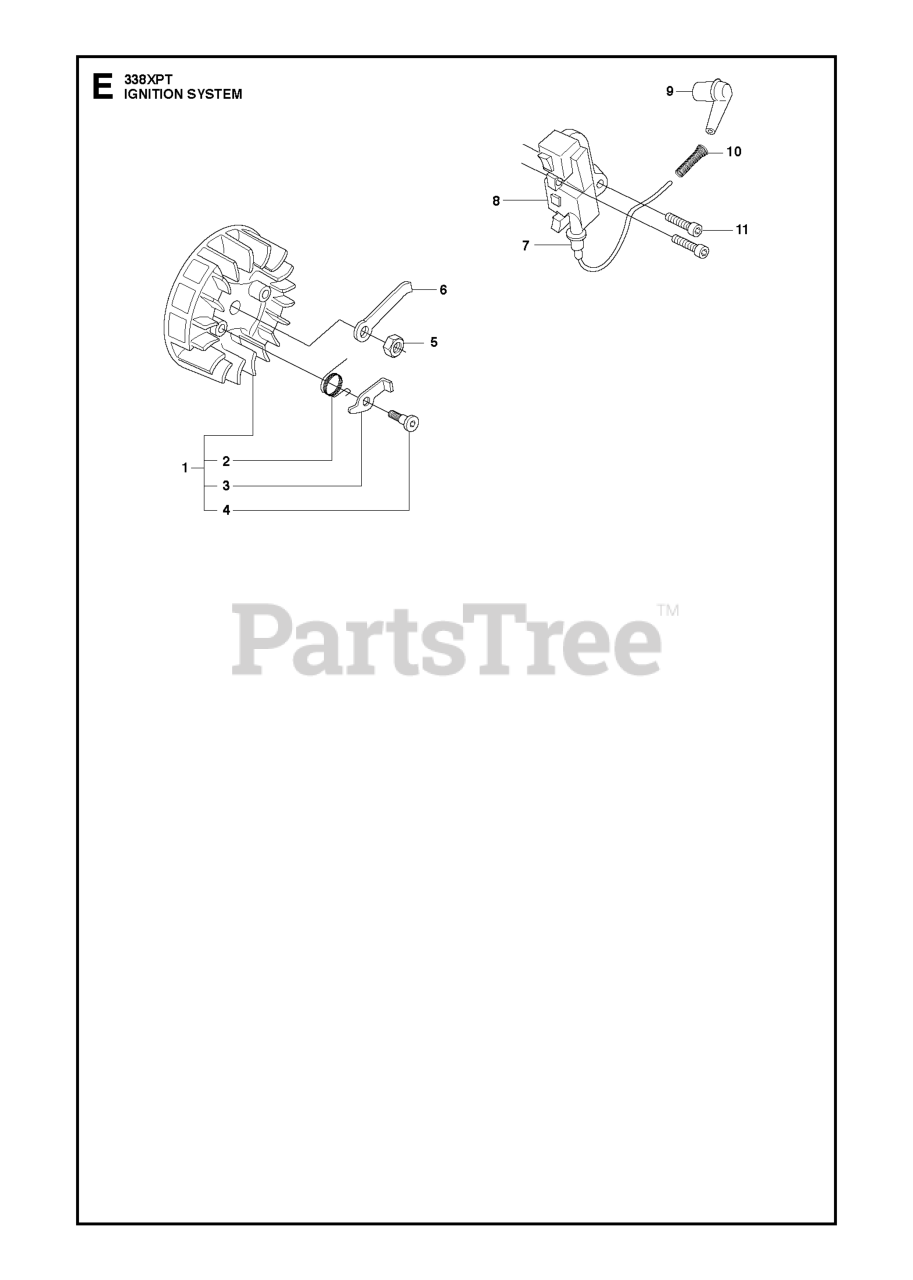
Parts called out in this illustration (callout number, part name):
7	CABLE GUIDE
8	IGNITION MODULE
9	SPARK PLUG CONN. KIT
10	CABLE COVER
